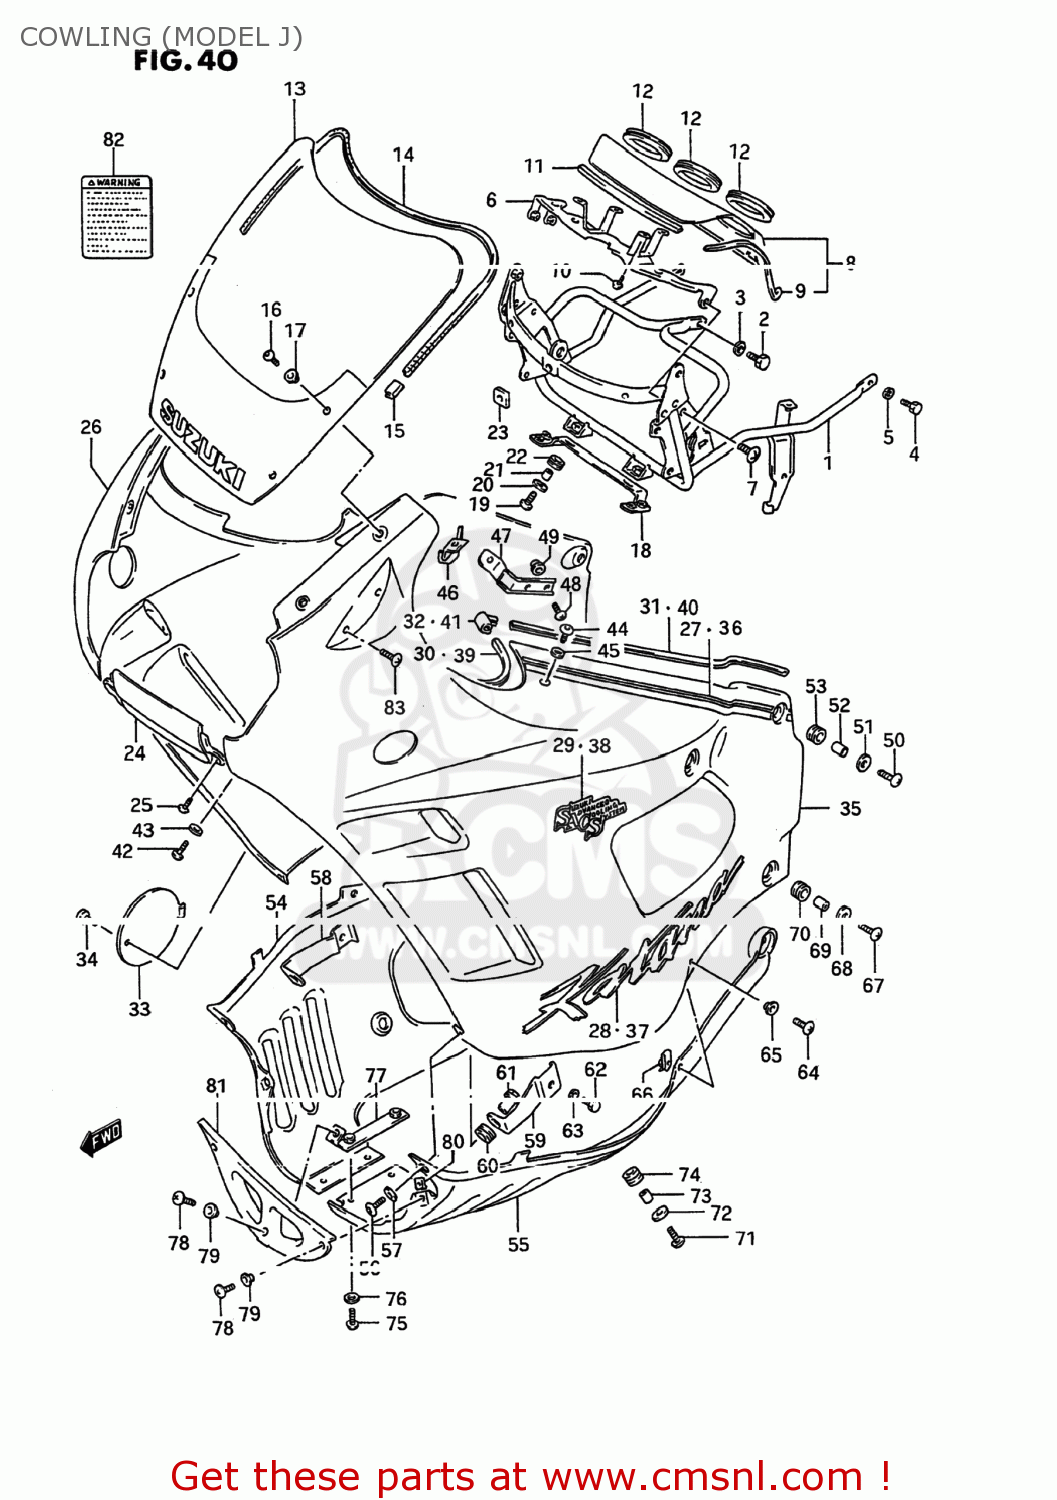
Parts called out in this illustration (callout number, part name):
1	BRACE,COWLING
2	BOLT
3	WASHER,LOCK,8.
4	BOLT
5	WASHER,LOCK
6	PLATE,METER FITING
7	SCREW 6X12
8	COVER,METER
9	MOLDING
10	SCREW 5X8
11	MOLDING,METER COVER
12	CUSHION,METER COVER
13	WINDOW,COWLING
14	MOLDING
15	CAP,MOLDING END
16	SCREW
17	WASHER(5.2X11X1)
18	PLATE,COWL CTR PANEL
19	SCREW, CENTER
20	WASHER (6.5X18X1.6)
21	SPACER (6,8X10X9.4)
22	CUSHION
23	CUSHION,SCREEN
24	PANEL,COWLING,CENTER
25	SCREW
26	COVER,COWLING R
27	TAPE SET,COWL,R
28	EMBLEM,KATANA
29	EMBLEM (SALS)
30	MOLDING
31	MOLDING
32	JOINT,MOLDING END
33	LID,OIL
34	SCREW(6X16)
35	COVER ASSY,COW
36	TAPE SET,COWLING,LEFT
37	EMBLEM,KATANA
38	EMBLEM (SALS)
39	MOLDING
40	MOLDING
41	JOINT,MOLDING END
42	SCREW(6X25)
43	WASHER(6.5X18X1.5)
44	SCREW(6X16)
45	WASHER(6.3X16X1.5)
46	BRACKET,COWLING UPR,R
47	BRACKET,COWLING UPR,L
48	SCREW(6X25)
49	NUT,COWLING SIDE BRKT
50	SCREW(6X25)
51	WASHER(6.5X18X1.5)
52	SPACER (6.1X9X9)
53	CUSHION
54	COVER,COWLING,UNDER,RIGHT
55	COVER,COWLING UNDER,L
56	SCREW(6X30)
57	WASHER(6.5X18X1.5)
58	BRACKET,COWLING LWR,R
59	BRACKET,COWLING LWR,L
60	CUSHION
61	NUT,COWLING,FR
62	BOLT 6X16
63	WASHER,LOCK
64	SCREW(5X18)
65	WASHER(5.2X14X1.5)
66	NUT,HEADLAMP HOUSING,UPPER
67	SCREW(6X25)
68	WASHER(6.5X18X1.5)
69	SPACER(6.1X9X12.3)
70	CUSHION
71	SCREW, CENTER
72	WASHER (6.5X18X1.6)
73	SPACER (6.1X9X9)
74	CUSHION
75	SCREW
76	WASHER,5MM
77	BRACKET,FR UNDER COWL
78	SCREW
79	WASHER(5.2X14X1.5)
80	NUT,HEADLAMP HOUSING,UPPER
81	COVER,COWLING,UNDER,FRONT
82	LABEL (WARNING SCREEN)
83	SCREW 6X12
